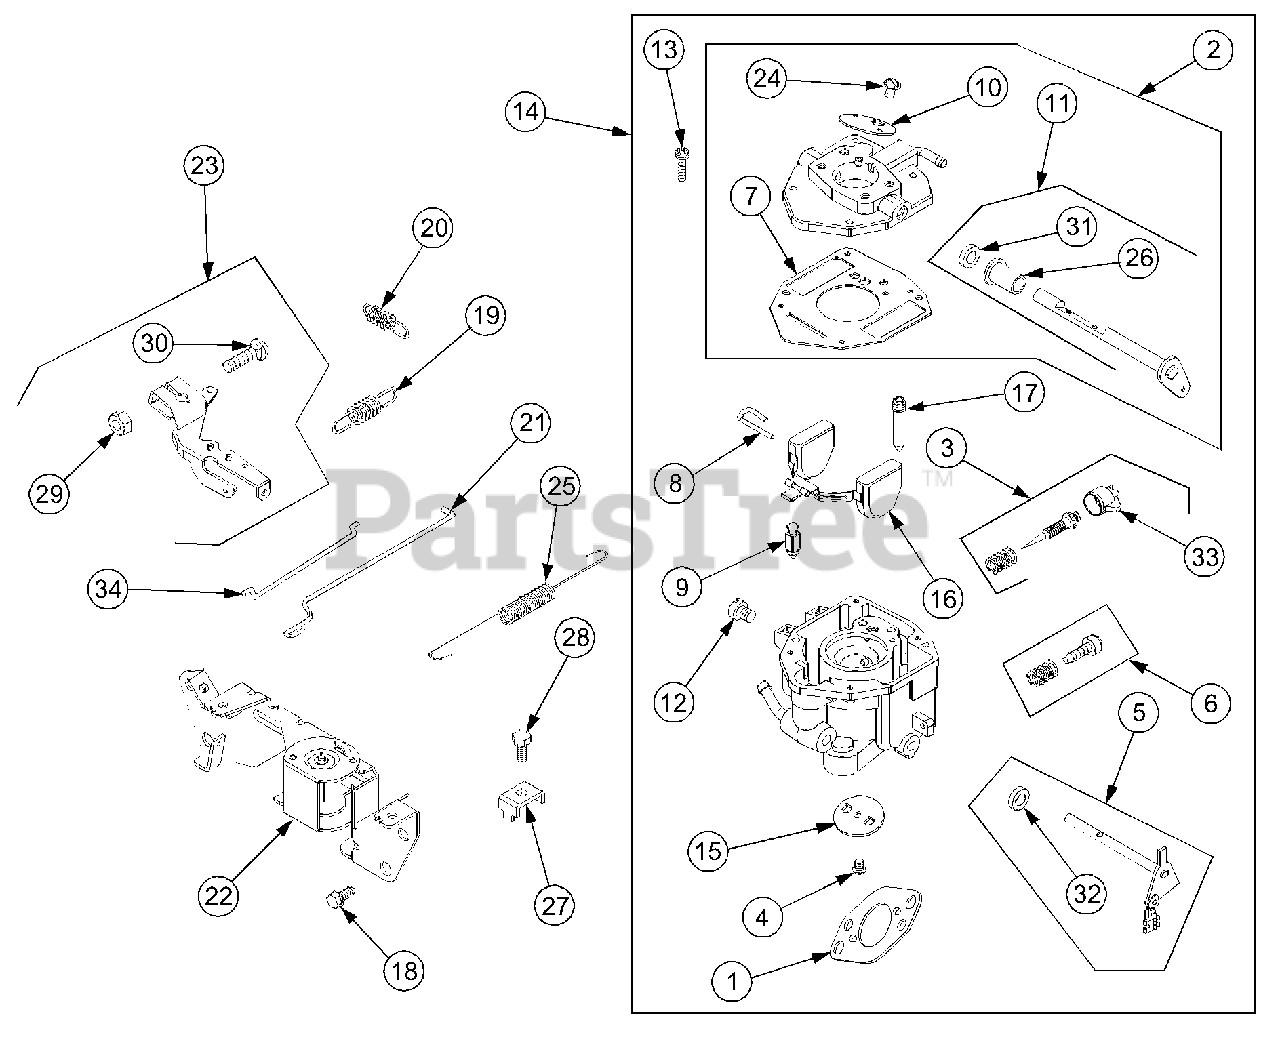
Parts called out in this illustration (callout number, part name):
1	Gasket, Intake
2	Body, Upper Carburetor
3	Kit, Idle Mixture
4	Screw, Throttle Valve
5	Shaft, Throttle
6	Kit, Idle Speed
7	Gasket, Carburetor Body
8	Pin, Float Hinge
9	Valve, Float Needle
10	Valve, Choke
11	Shaft, Choke
12	Jet, Main (Standard)
14	Carburetor
15	Valve, Throttle
16	Float, Carburetor
17	Nozzle, Carburetor
19	Spring, Governor
20	Spring, Governed Idle
21	Link, Throttle
22	Bracket, Control
23	Lever, Governor Control
24	Screw, Choke Valve
25	Spring, Governor Link
26	Bushing, Choke Shaft
27	Clamp, Casing
29	Nut, Governor Control Lever
30	Bolt, Governor Control Lever
31	Seal, Choke/Throttle Shaft
32	Seal, Choke/Throttle Shaft
33	Cap, Limiter
34	Link, Choke
